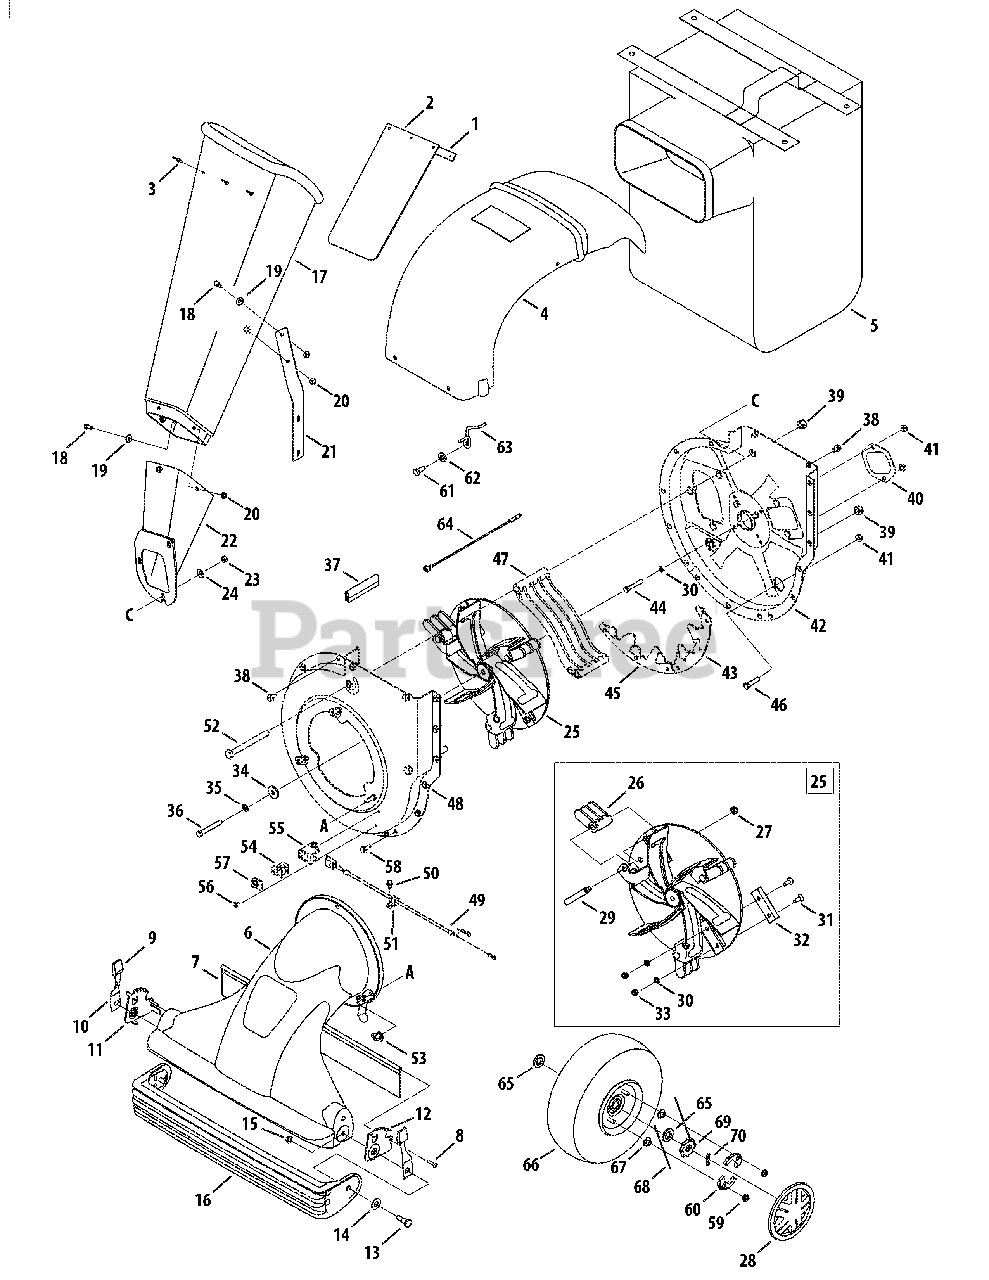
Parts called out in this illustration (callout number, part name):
1	Chute Flap Strip
2	Chute Flap
3	Pop Rivet
4	Discharge Chute
6	Nozzle Assembly
7	Nozzle Flap
9	Height Adjustment Knob
10	Spring Lever
11	Index Bracket RH
12	Index Bracket LH
13	Shoulder Screw
14	Flat Washer, .510 x 1.12 x.060
15	Hex Flange Lock Nut, 3/8-16
16	Door Assembly
17	Chipper Chute
18	Hex Cap Screw, 1/4-20 x.620
19	Flat Washer, .28 ID x.74 OD
20	Hex Lock Nut, 1/4-20
21	Support Bracket
22	Chipper Chute Assembly
23	Hex Nut, 5/16-18
24	Belleville Washer, .340ID x.872OD
25	Impeller Assembly: Complete
26	Flail Blade
27	Jam Lock Nut, 3/8-16
29	Shoulder Pin, .5 x 2.625
30	Lock Washer, 5/16
31	Cap Screw 5/16-24 x 1.0
32	Chipper Blade
33	Hex Lock Nut 5/16-24
34	Flat Washer, .406 x 1/1/4
35	Lock Washer, 3/8
36	Hex Cap Screw, 3/8-24 x 2.75
37	Rubber Seal
38	Hex Washer Screw, 5/16-18
39	Hex Lock Nut, 1/2-13
40	Chipper Blade Cover
41	Hex Flange Lock Nut 5/16-18
42	Housing Assembly: Inner Flail
43	Upper Shredder Blade
44	Hex Cap Screw, 5/16-18 x 2
45	Flail Housing Blade
46	Hex Cap Screw, 5/16-18 x.75
47	Discharge Screen
48	Housing Assembly: Outer Flail
49	Wire Harness
50	TT Screw, 1/4-14 x 0.625"
52	Hex Cap Screw, 1/2-13 x 5.0
53	Knob, 5/16-18
55	Safety Switch Mounting Cover
56	Hex Washer Screw
57	Switch Cover
58	LD Screw, 5/16-18 x 0.75"
59	Hex Flanged Lock Nut, 1/4-20
60	Pawl, .345 ID -LH
60	Pawl, .345 ID - RH
61	Hex Cap Screw, 5/16-24 x.75
62	Flat Washer, .344 x.75 x.12
63	Belt Keeper
64	Adapter Harness Assembly
65	Flat Washer, 5/8 ID x 1.0 OD
66	Wheel Complete 10 x 4 x 4
67	Hex Nut, 1/4-20
68	Plastic Spring Ratchet
69	Wheel Ratchet 1.62 OD x.5 serr
70	Cotter Pin
